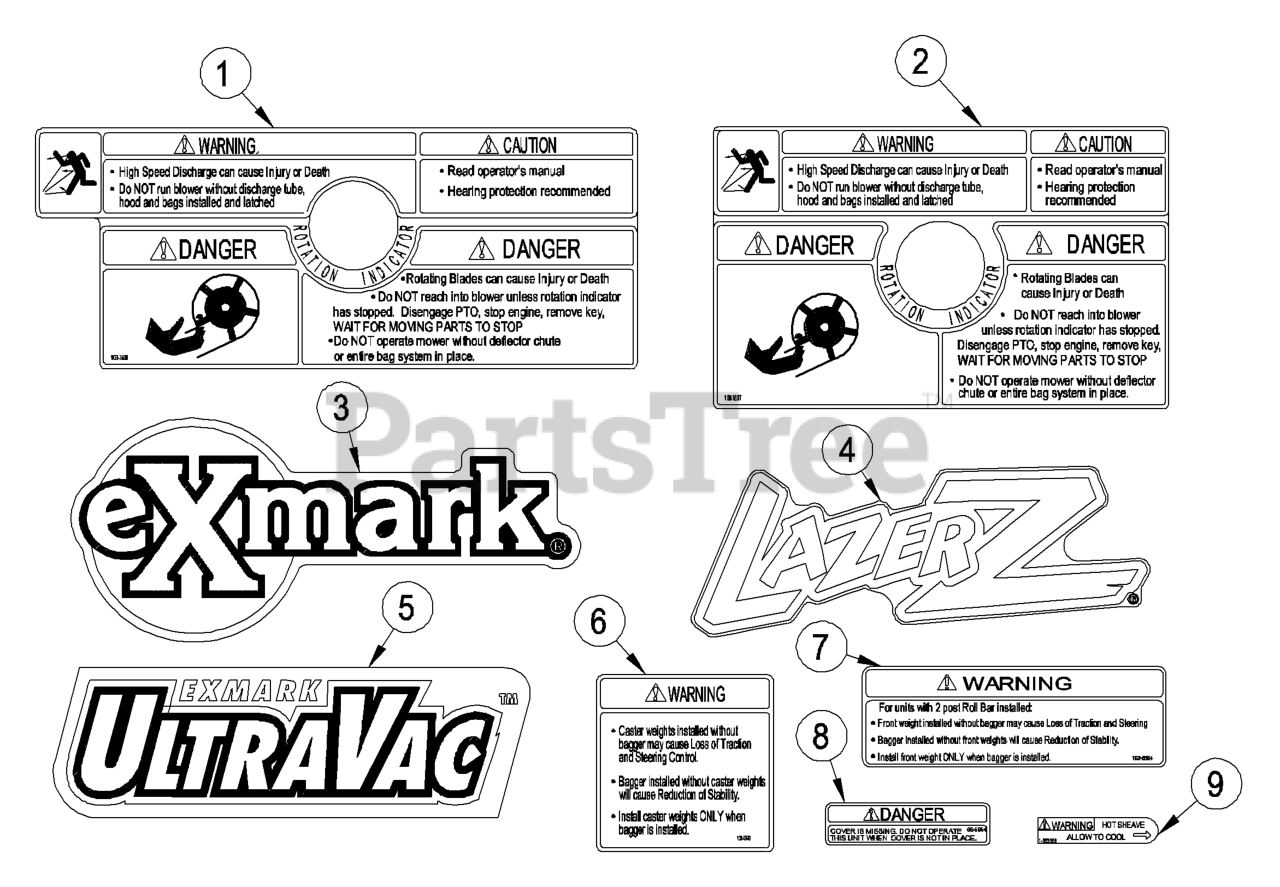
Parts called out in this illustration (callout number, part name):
1	DECAL-WARNING
3	DECAL, EXMARK LOGO
4	DECAL,LAZER MODEL
5	DECAL, ULTRAVAC
8	DECAL-COVER, MISSING
9	DECAL-WARNING
